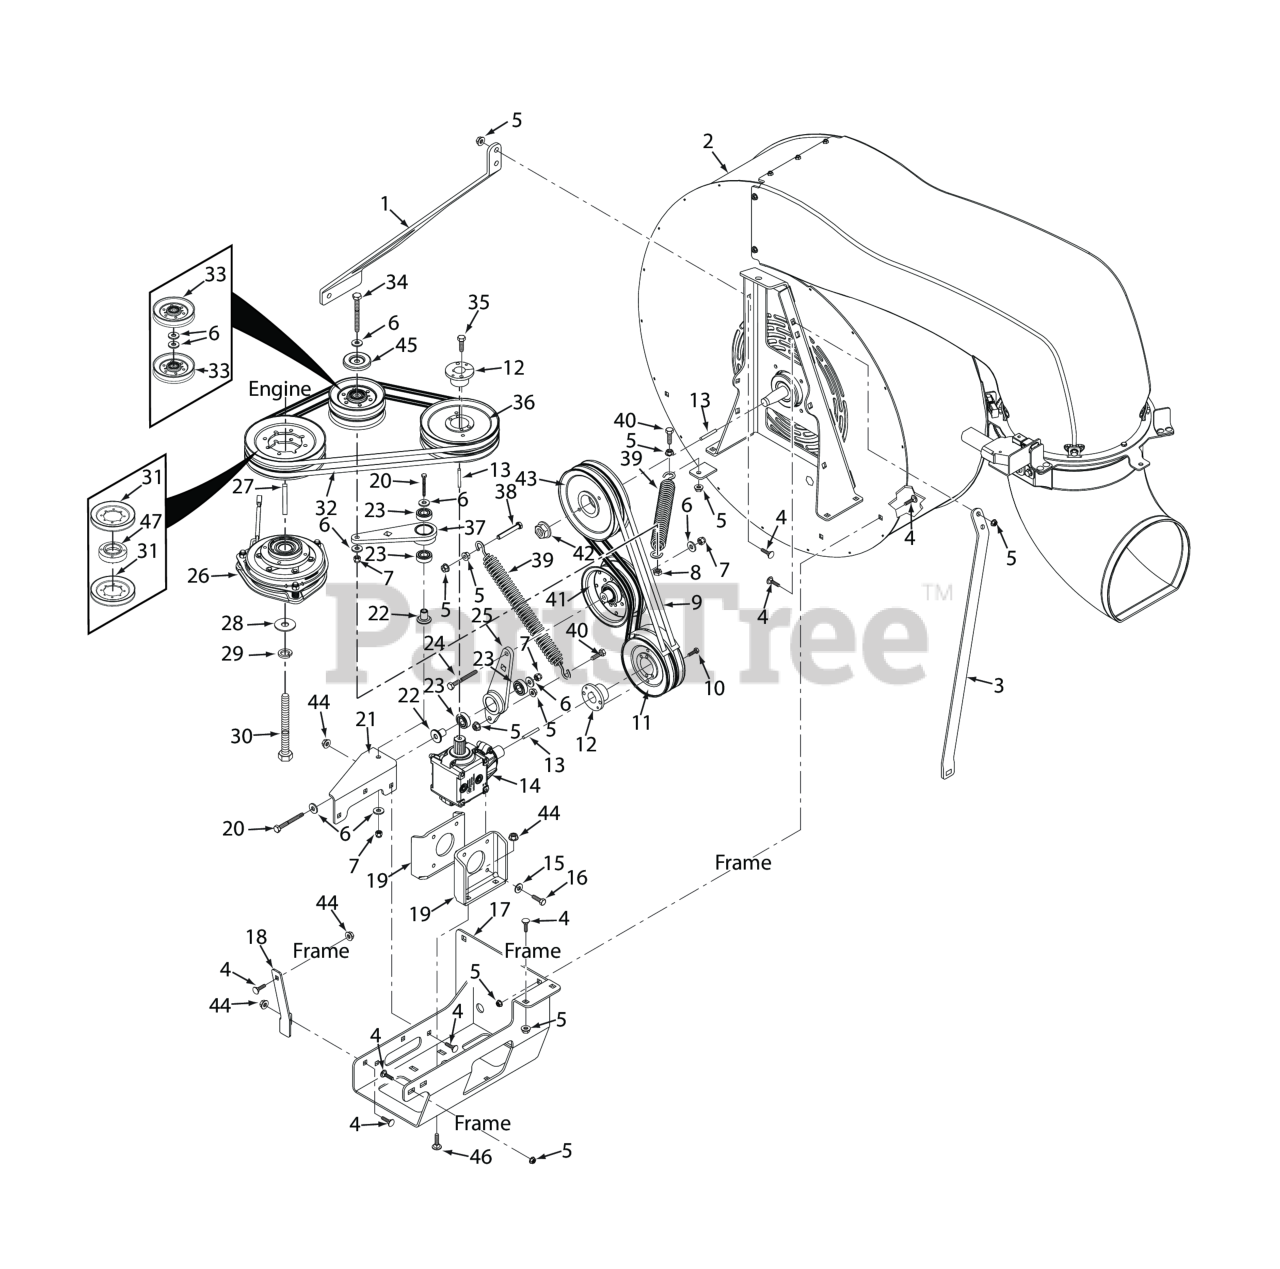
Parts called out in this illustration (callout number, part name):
1	LH Support Bar, Blower
2	Blower Housing, With Decal
3	RH Support Bar, Blower
4	Carriage Bolt, 3/8-16 x 1.0"
5	NUT, 3/8-16 SERRATED FLANGE HEX HEAD
6	Flatwasher, 3/8 (.391 x .938 x .105 HD) Grade 8
7	HEX NUT, ELASTIC STOP LOCK, 3/8-16
8	Bolt, Hex Head 3/8-16 x 1" Ser. Flg.
9	C-Belt, Gearbox Output
10	Hub, Tapered, 1" Bore
11	Pulley, Double Groove
12	TAPERED HUB, 1.00" BORE
13	Key, 1/4 x 1/4 x 1.25" Pulley Mtg.
14	Gearbox Assembly
15	Lockwasher, 5/16 (.317 x .586 x .078) Helical Spring
16	Bolt, Heax Head 5/16-18 x 1" (48V / 52V)
17	Mounting Bracket, Gearbox
18	Support Strap, Gearbox
19	Mounting Plate, Gearbox
20	Bolt, Hex Head 3/8-16 x 2-1/4" - 61"
21	Idler Arm Bracket, Gearbox
22	Pivot, Idler Short
23	BEARINGS, BALL, NEUTRAL RETURN
24	Bolt, Hex Head 3/8-16 x 3" - 52"
25	Idler Arm Assembly, Gearbox Output (INCL. 23)
26	Clutch, GT3.5 (28.6mm Bore)
27	Key, 1/4 x 1/4 x 3-1/2"
28	Flatwasher, 7/16-.469 x 1.75 x .25 (48, 52)
29	Lockwasher, 7/16� Spring
30	Bolt, Hex Head 7/16-20 x 3" w/t Patch
31	Pulley, Clutch 7.30 DIA
32	Belt, Gearbox Input
33	IDLER PULLEY, "V" GROOVE
34	Capscrew, Hex Head 3/8-16 x 3-3/4"
35	Bolt, Hex Head 1/4-20 x 1" Grade 8 Black
36	Pulley, Gearbox Input, 6.95 DIA, Double Groove
37	Idler Arm Assembly, Gearbox Input (INCL. 23)
38	Bolt, Hex Head 3/8-16 x 2-1/2" Grade 8
39	Spring, Transmission Drive
40	Bolt, Hex Head 3/8-16 x 1-1/2" Grade 8 Black
41	Pulley, Idler 5" Dia.
42	Nut, 3/4-16 Spriral Lock
43	Pulley, Blower, 6.95 DIA, Double Groove
44	Nut, Flange Elastic Stop Nut, 3/8-16
45	Quick Pin, 5/16" Dia.
46	Bolt, Carriage 3/8-16 x 1"
47	Hub, Clutch Pulley
